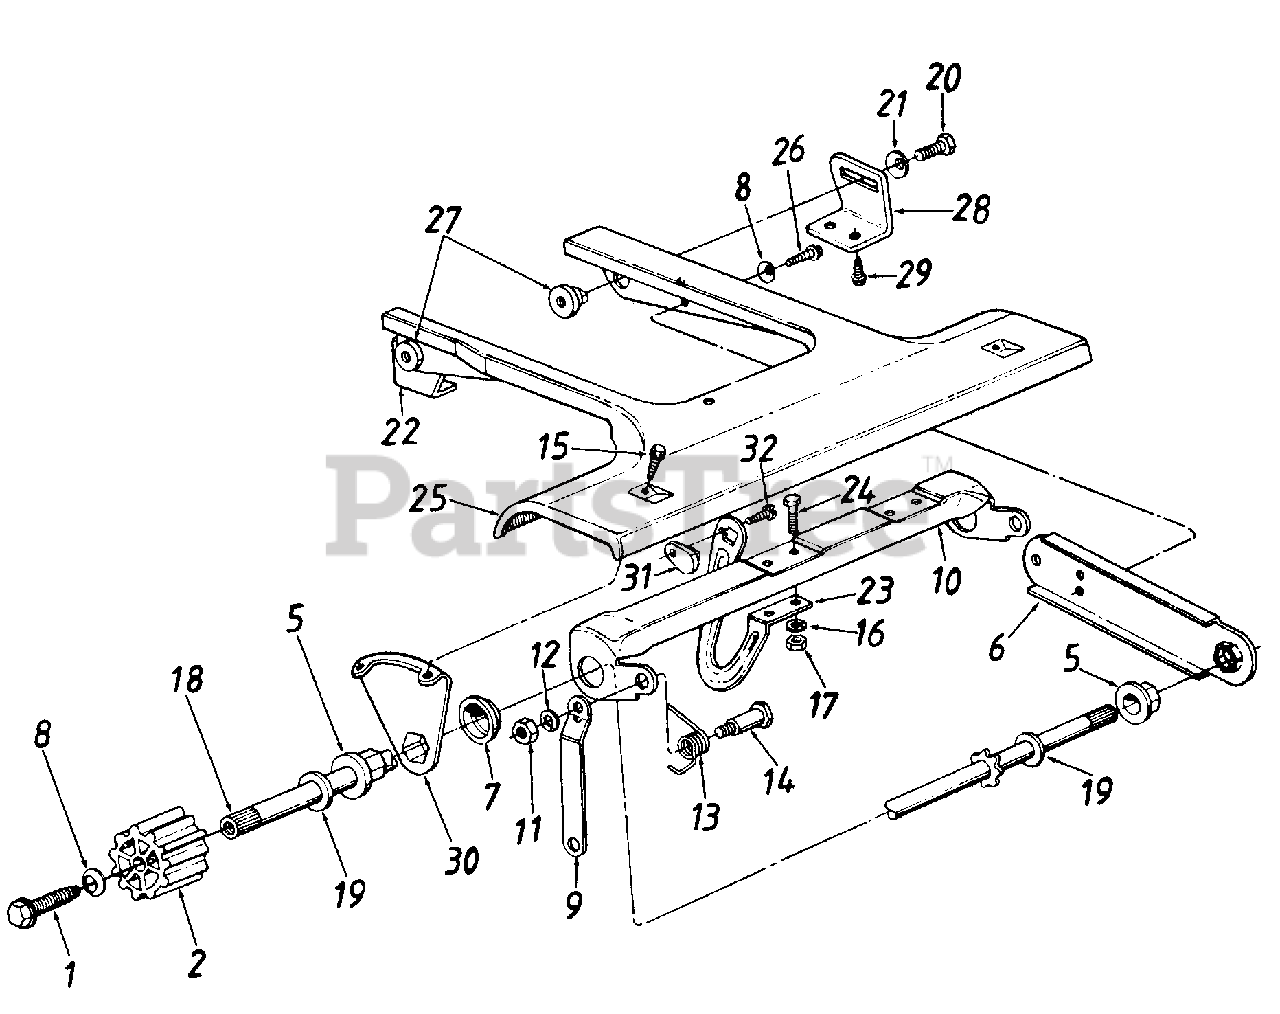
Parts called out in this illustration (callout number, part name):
1	Hex Wash. Hd. Tap Scr. 1/4-20 x .75" Lg.
2	Wheel Drive Pinion-Half
5	Hex Flange Brg. .504" I.D.
8	Bell-Wash. .265" I.D. x .75" O.D.
9	Link 5.06" Lg.
10	Drive Engagement Cam
11	Hex Nut 5/16-18 Thd.
12	L-Wash. 5/16" I.D.
13	Torsion Spring-R.H.
14	Shoulder Bolt .437" Dia.
15	Hex AB-Tap Scr. 1/4 x .62 Lg.
16	L-Wash. 1/4" I.D.
17	Hex Nut 1/4-20 Thd.
18	Drive Shaft Ass'y.
19	Fl-Wash. .531" I.D. x .93" O.D.
20	Hex Bolt 5/16-18 x .62" Lg.
21	Bell-Wash. .345" I.D. x .88 O.D.
22	Pivot Bracket-R.H.
25	Front Pinion Pivot Cover
27	Shoulder Nut
28	Pivot Bracket-L.H.
29	Hex Wash. Hd. AB-Tap Scr. 1/4 x.62" Lg.
32	Hex B-Tap Scr. #10 x .44"
